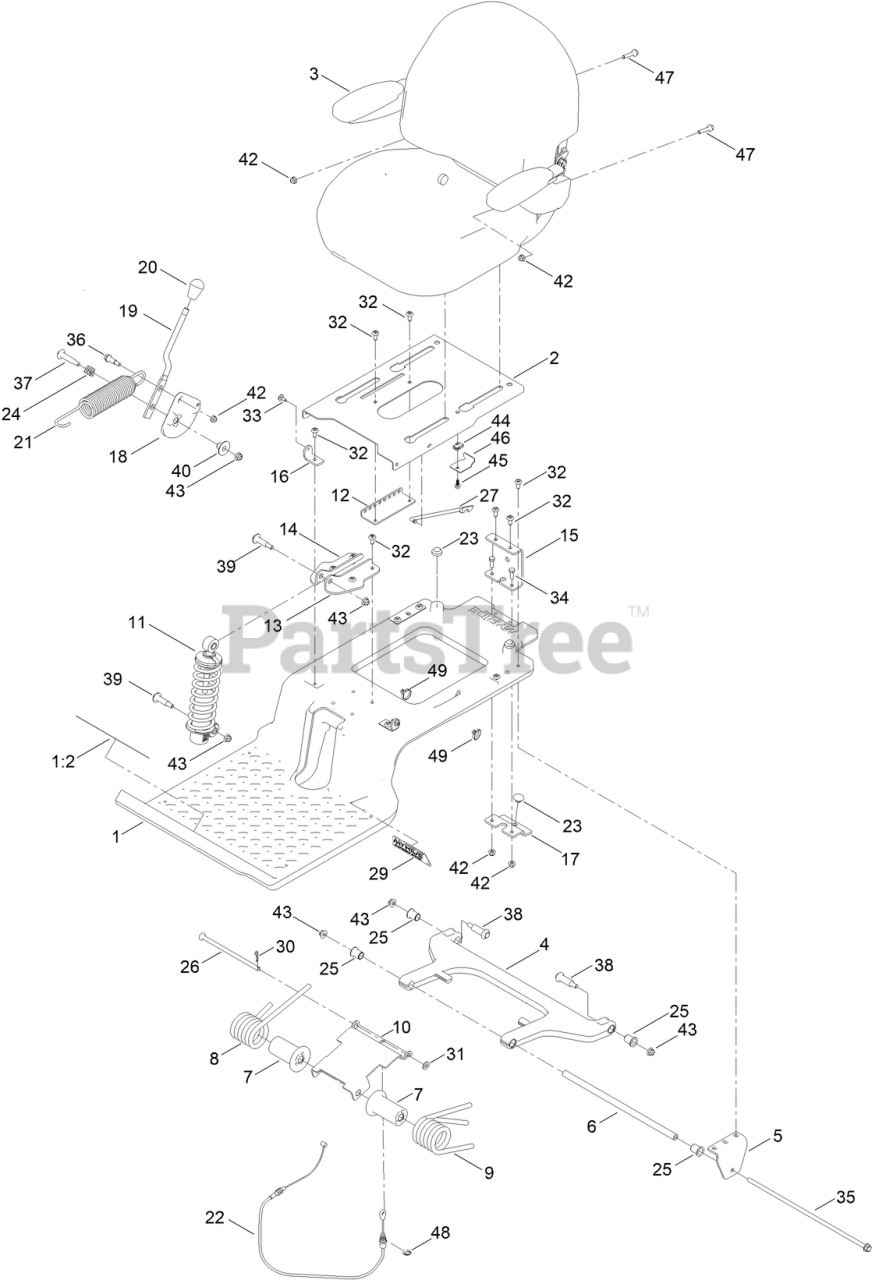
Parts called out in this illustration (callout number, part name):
1	SUBFRAME ASM
1:2	DECAL-DANGER
2	PAN-SEAT
3	SEAT ASM
4	ARM, SWING
5	BRACKET-MOUNT, SWING ARM
6	TUBE-SPACER
7	RETAINER-SPRING
8	SPRING-TORSION, RH
9	SPRING-TORSION, LH
10	PLATE-ADJUSTER
11	SHOCK/SPRING ASM
12	BRACKET-LATCH, SEAT
13	BRACKET-SHOCK MOUNT, UPPER (LH)
14	BRACKET-SHOCK MOUNT, UPPER (RH)
15	BRACKET-CABLE
16	BRACKET-SEAT
17	BRACKET LOWER
18	PULLEY - CAM
19	LEVER - ADJUSTMENT
20	KNOB-MR
21	SPRING-EXTENSION
22	CABLE-ADJUSTMENT, MYRIDE
23	BUMPER-SEAT
24	SPRING-COMPRESSION
25	BUSHING-FLANGE
26	ROD-ADJUSTMENT
27	ROD-PROP, SEAT
29	DECAL-MYRIDE
30	PIN-COTTER
31	WASHER-FLAT
33	SCREW-SHOULDER
34	SCREW-HH
35	SCREW-HHF
36	BOLT-SHOULDER, HHF
37	BOLT-SHOULDER
38	BOLT-SHOULDER
39	BOLT-SHOULDER
40	BUSHING - FLANGE
42	NUT-HF, NI
43	NUT-HF, NI
45	SCREW-HHF
46	BRACKET-STOP, SEAT
47	SCREW-HHF
48	RING-RETAINING, EXTERNAL
49	TIE-CABLE
